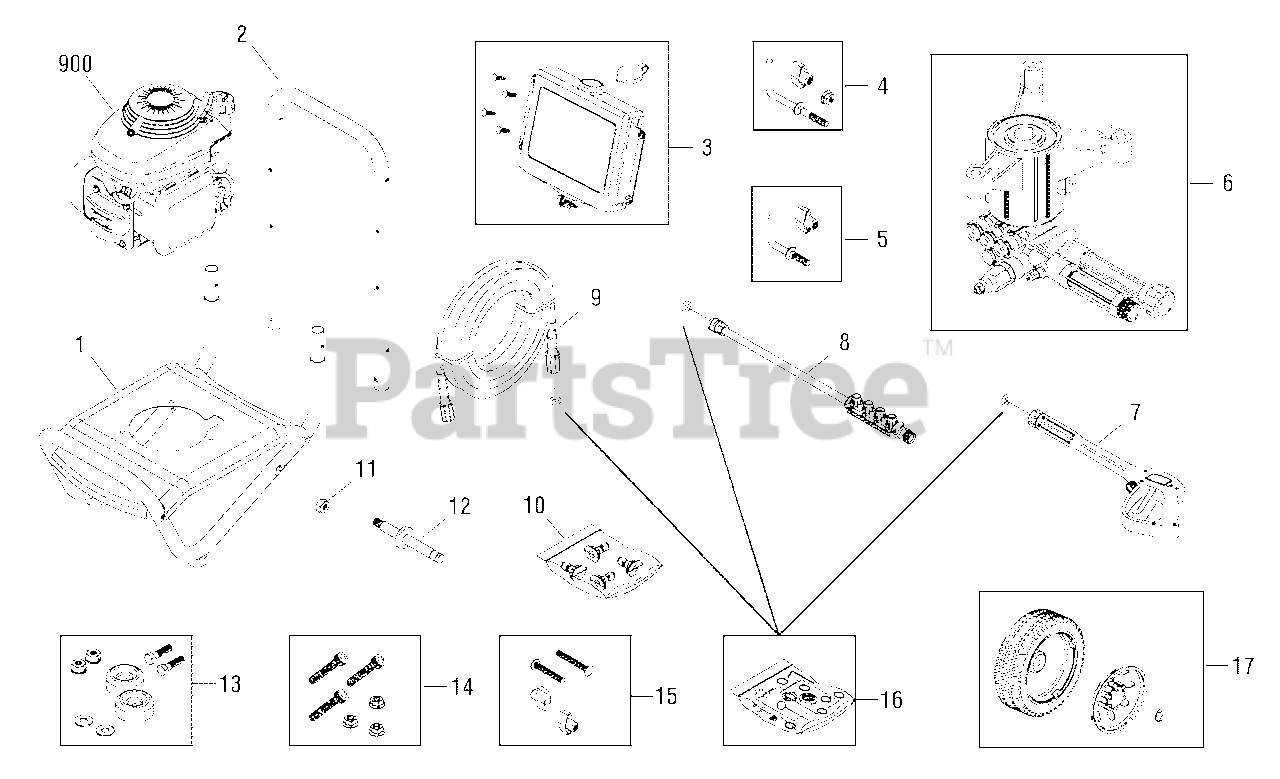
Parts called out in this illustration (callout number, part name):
6	PUMP
7	GUN
8	EXTENSION, QC
9	HOSE
10	KIT, QC Nozzles
11	NUT
12	AXLE
13	MOUNT, Vibration
14	KIT, Hardware, Pump Mounting
15	KIT, Hardware, Handle
16	KIT, O-Rings
900	ENGINE
